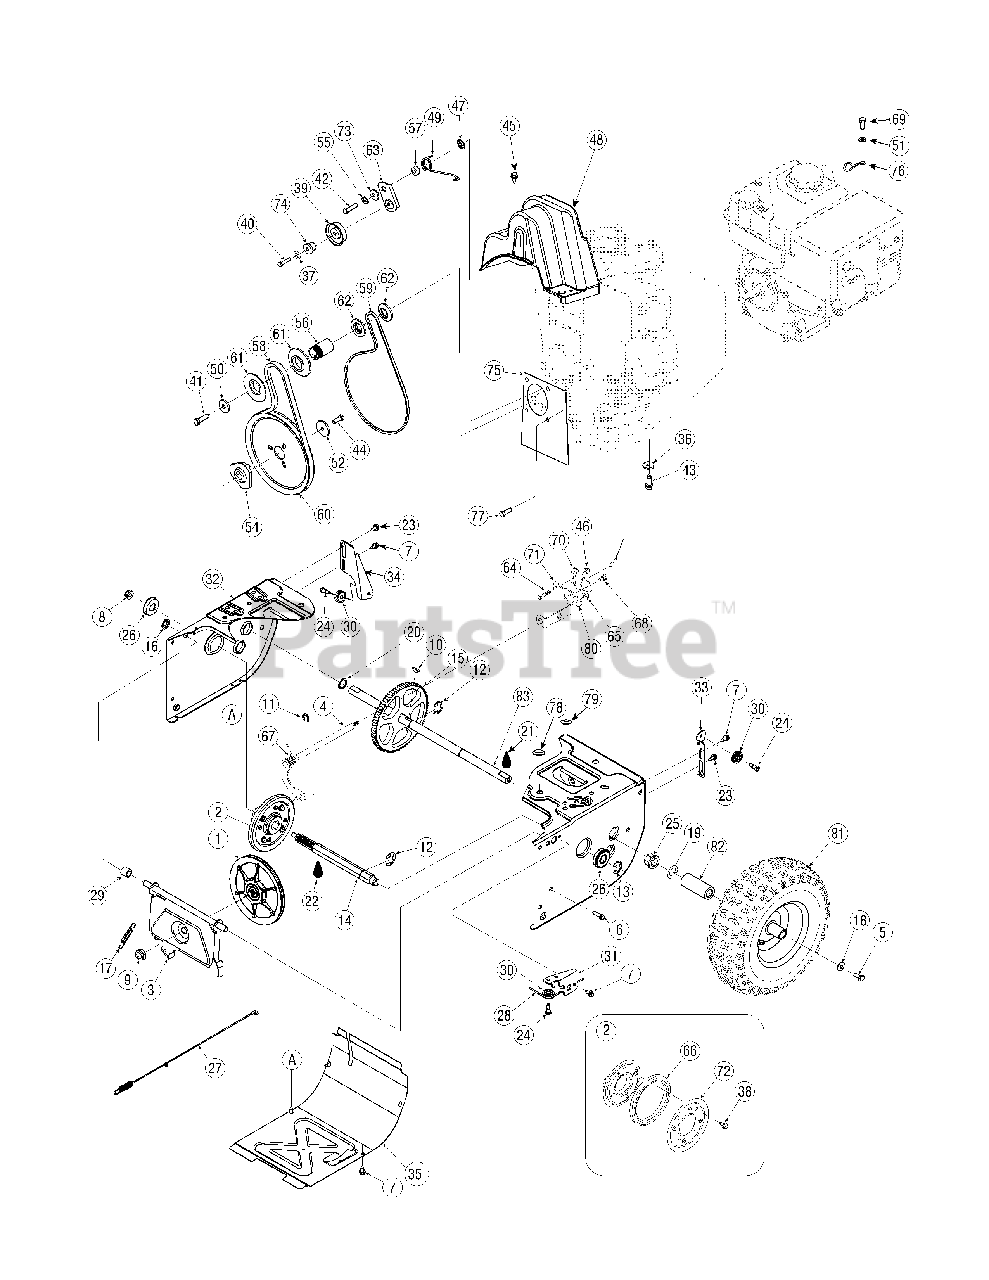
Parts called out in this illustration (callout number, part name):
1	Friction Wheel Disc Assembly
2	Friction Wheel Ass’y, Bearing 5.5 OD
4	Shift Rod Ass’y
5	Hex L-Bolt 5/16-24 x .75 Gr. 5
6	Hex Bolt 1/4-20 x 1.00
7	Hex Wash Hd TT Screw 1/4-20 x .625
8	Flange Lock-Nut 3/8-16 Gr. F Nylon
9	Jam L-Nut 5/8-18
10	#9 HI-Pro Key 3/16 x 3/4 Dia HT
11	Retaining Ring
12	Retainer Ring
13	"E" Ring
14	Hex Shaft .8125 - 7 tooth
15	Gear - 80 Tooth
16	Cap Speed Nut 1/4 Rod
17	Extension Spring 3/8 OD x 2.50
18	Cupped Washer .345 ID x .88 OD x .060
19	Flat Washer .79 ID x 1.25 OD x .06
20	Flat Washer .75 x 1.00 x .06
21	Grease
22	Rust Preventative Oil
23	Shoulder Screw .373 x .105:TT 1/4-20
24	Hex Shld.Screw1/4-28 x .375
25	Hex. Flange Bearing.751" ID
26	Ball Bearing w/snap ring
27	Drive Clutch Cable 44.83" Lg.
28	Auger Clutch Cable 47.23" Lg.
29	Spacer .513 ID x 1.0
30	Cable Guide Roller
31	Auger Cable Guide Bracket
32	Frame
33	Guide Bracket - Auger Cable
34	Guide Bracket - Drive Cable
36	Flat Washer .38 x 1.38 x .125 (Rear left hole)
37	L-Wash 1/4 ID
38	Hex Wash. Hd. TT Screw 1/4-14 x .625
39	Idler Pulley Assembly 1.917 OD
40	Hex Screw 1/4-20 x 1.25
41	Hex Screw 3/8-24 x 1.25
42	Hex Hd Cap Screw 5/16-24 x 1.25 Gr. 5
43	Hex Wash HD Tap Scr 3/8-16 x .88
44	Hex Bolt 5/16-24 x 0.875
45	Hex Wash Hd TT Screw 1/4-20 x .625
46	Hex L-Flanged Nut 1/4-20 Gr. F Nylon
47	Push Nut
48	Belt Cover (w/2 & 4 way chute control)
49	Torsion Spring .850 ID x .354" Lg.
50	Flat Washer .40 ID x 1.25 OD x .160
51	Flat Washer .330 ID x .630 OD x .0635
52	Flat Washer .34 x 1.50 x .150
53	Grease:Arc tic:EP NLGI 1-58F
54	Pulley Adapter
55	Lockwasher 5/16
56	Spacer .875 ID x 1.185 OD
57	Spacer .340 x .750 x .360" Lg.
58	Belt .5 x 35.0" Lg.
59	Belt 3/8 x 34.4" Lg.
61	Pulley Half
62	Pulley Half 3/8 V x 1.71 OD
63	Wheel Drive Idler Bracket
64	Hex Bolt 1/4-20 x .62 Gr. 5
65	Flange Locknut 5/16-18 Gr. F, Nylon
66	Friction Wheel Rubber
67	Torsion Spring .750 ID x .968" Lg.
68	Shoulder Screw .373 x .105:TT 1/4-20
69	Hex. Hd. Cap Screw M8-1.25:20 Gr. 8
70	Pivot Bracket
71	Shift Bracket
72	Friction Plate
73	Shld. Spacer .3175 x .5 x .1025
75	Cover Plate (Optional)
76	Cable control Wire
77	Shoulder Screw .50 x .145: 5/16-24
80	Flat Washer .469 x .875 x .105
